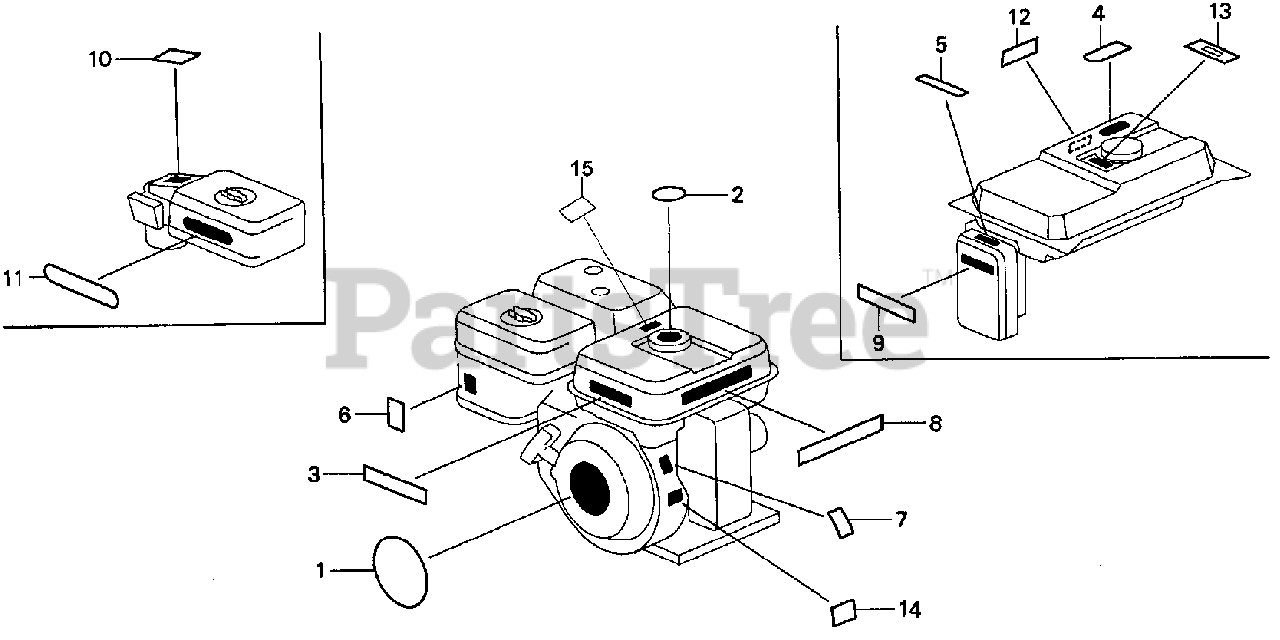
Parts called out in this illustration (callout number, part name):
1	EMBLEM (INTERNAL)
1	EMBLEM (5.5)
6	MARK, CHOKE
7	LABEL, SPECIFICATION (EXTERNAL)
8	MARK, OIL ALERT (GERMAN)
8	MARK, OIL ALERT (FRENCH)
8	MARK, OIL ALERT (E)
15	LABEL, FUEL CAUTION
